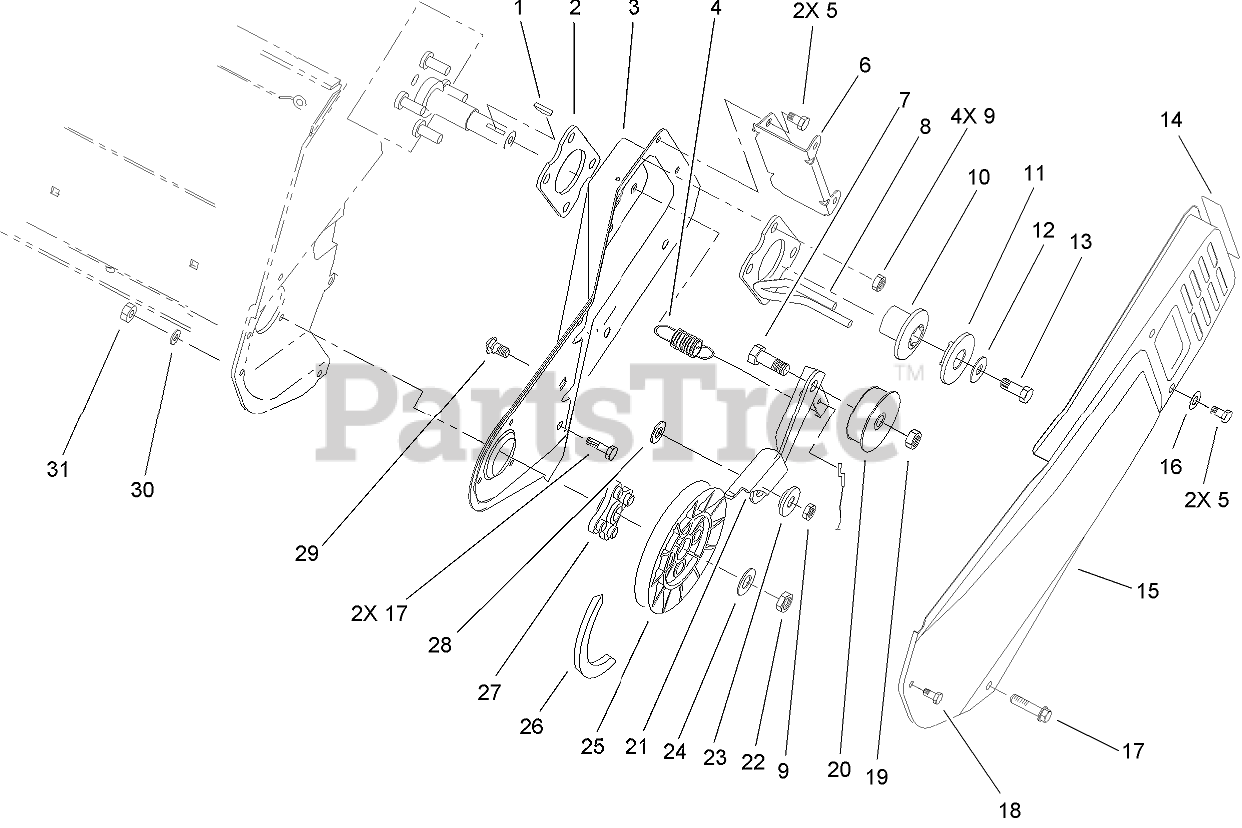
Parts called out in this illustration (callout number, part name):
1	KEY-WOODRUFF
2	PLATE-ENGINE
3	SIDEPLATE-LH
4	SPRING-BRAKE
5	SCREW-HWH
6	BRACKET-COVER, BELT
7	SCREW-HH
8	GUIDE-BELT
9	NUT-LOCK, NI
10	Hub-HALF SHEAVE
11	CAP-HALF SHEAVE
12	WASHER-FLAT
13	SCREW-HH
14	DECAL-HOT
15	COVER-BELT
16	WASHER-FLAT
17	SCREW-PLASTIC
19	NUT-LOCK, NI
20	PULLEY-IDLER
21	ARM-BRAKE
22	NUT-LOCK, NI
23	BUSHING-IDLER
24	WASHER-FLAT
25	PULLEY-DRIVEN
26	V BELT
28	WASHER
29	SCREW-CARR
30	WASHER-FLAT
31	NUT-LOCK, NI
